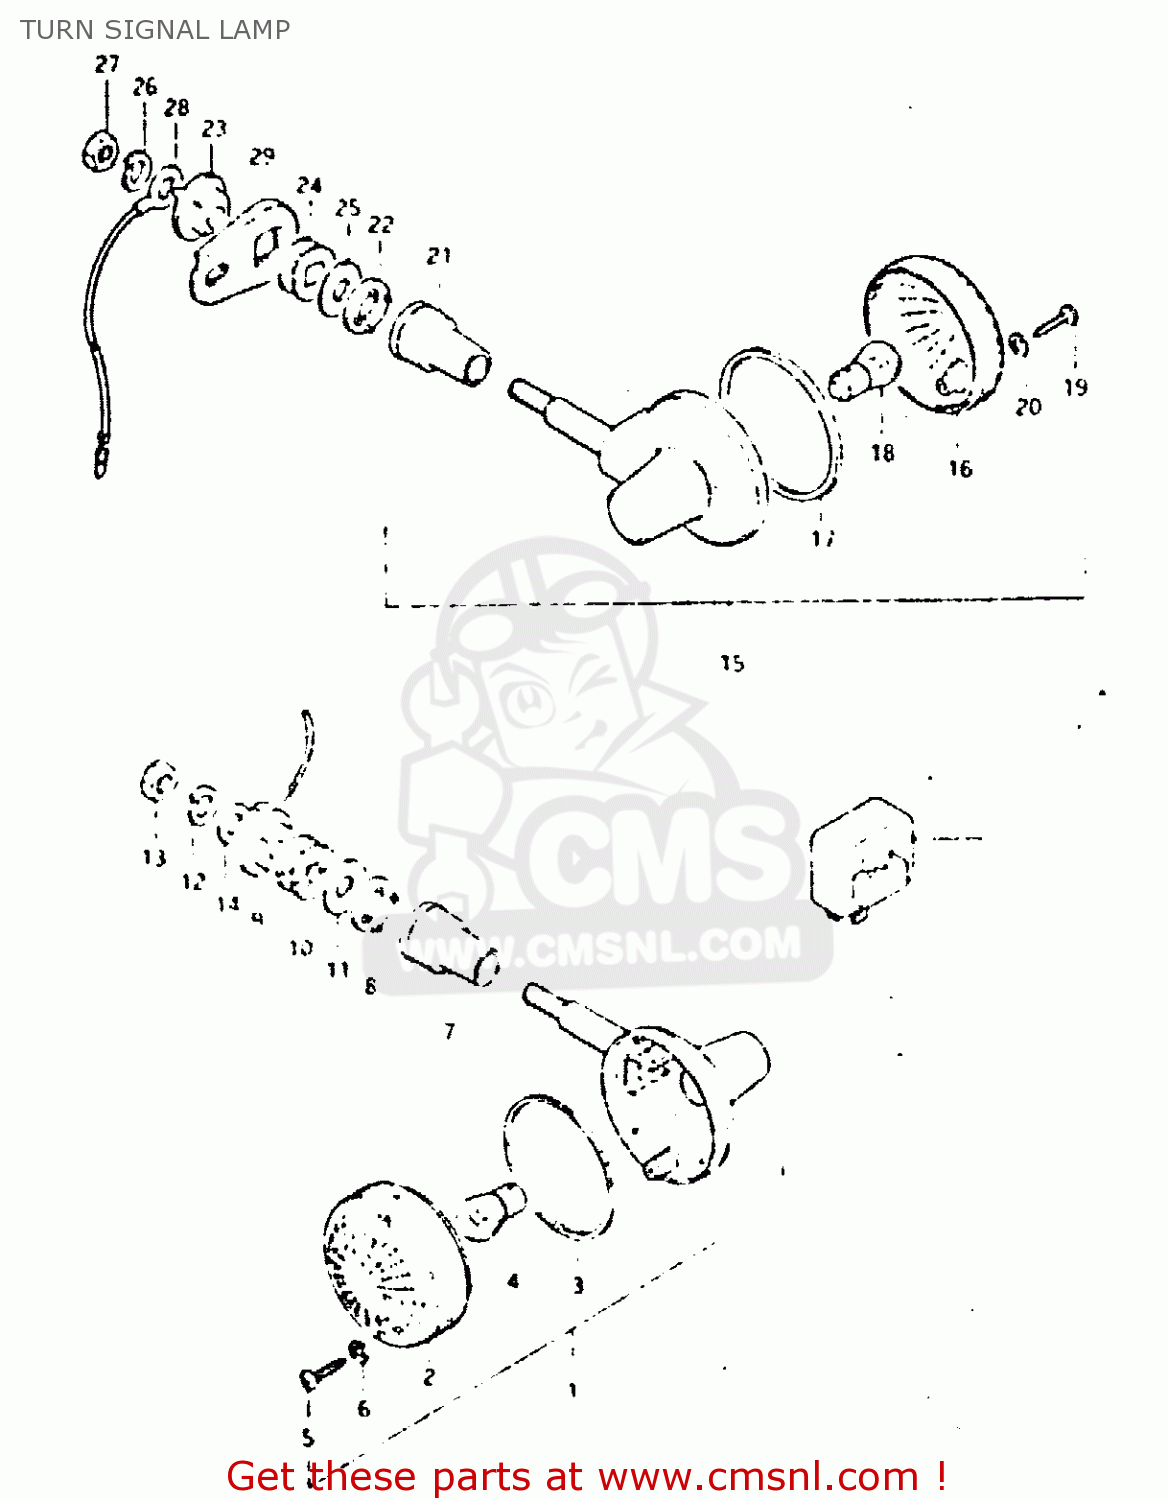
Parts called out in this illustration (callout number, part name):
1	LAMP, FRONT TURN SIGNAL
2	LENS
3	GASKET (NAS)
4	BULB 12V 21W
5	SCREW
6	GASKET (NAS)
7	COVER,STAY
8	SPACER
9	SPACER
10	CUSHION
11	WASHER (10.5X30X2.3)
12	LOCK WASHER
13	NUT
14	WIRE
15	LAMP, REAR TURN SIGNAL
16	LENS
17	GASKET (NAS)
18	BULB 12V 21W
19	SCREW
20	GASKET (NAS)
21	COVER,STAY
22	SPACER
23	SPACER
24	CUSHION
25	WASHER (10.5X30X2.3)
26	LOCK WASHER
27	NUT
28	WIRE
29	BRACKET,RR TURN SIGNAL LAMP
30	RELAY, TURN SIGNAL
